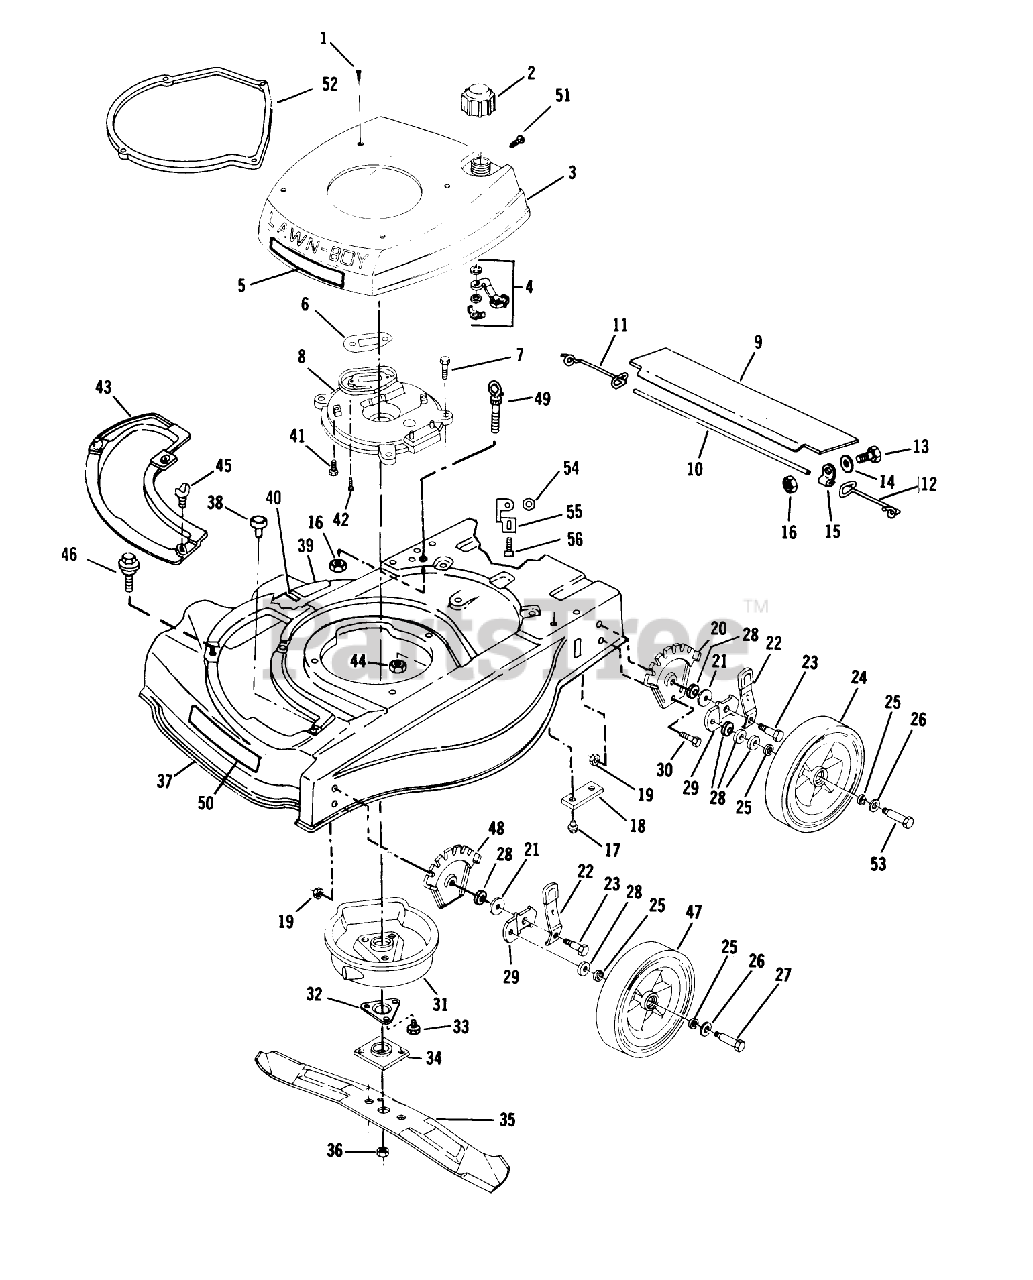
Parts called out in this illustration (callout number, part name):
1	SCREW LAWRENCE
2	FUEL CAP & INSERT
7	SCREW-HH
8	PLATE,MUFFLER F
10	ROD T/SHIELD ADV WIRE
11	SPRING;TRAILING SHIELD RH
12	SPRIG T/SHLD ASOC
14	Washer-Trailing Shield
15	CLAMP ROD KMC
16	LOCKNUT E
17	SCREW
19	LOCKNUT
21	WASHER
22	KNOB&SPRING FORMCO
23	BOLT
25	WASHER
26	SPACER
27	BOLT WHEEL
28	WASHER WROUGHT
32	SUPPORT F
33	SCREW
34	PLATE AND COLLAR ASM
36	NUT-BLADE
42	SCREW V
44	NUT-LOCK F
45	WING SCREW LAWRE
47	WHEEL & TIRE KIT
48	PLATE HGT ADJ TRO
49	BOLT-EYE
51	SCREW S
54	LOCKNUT E
